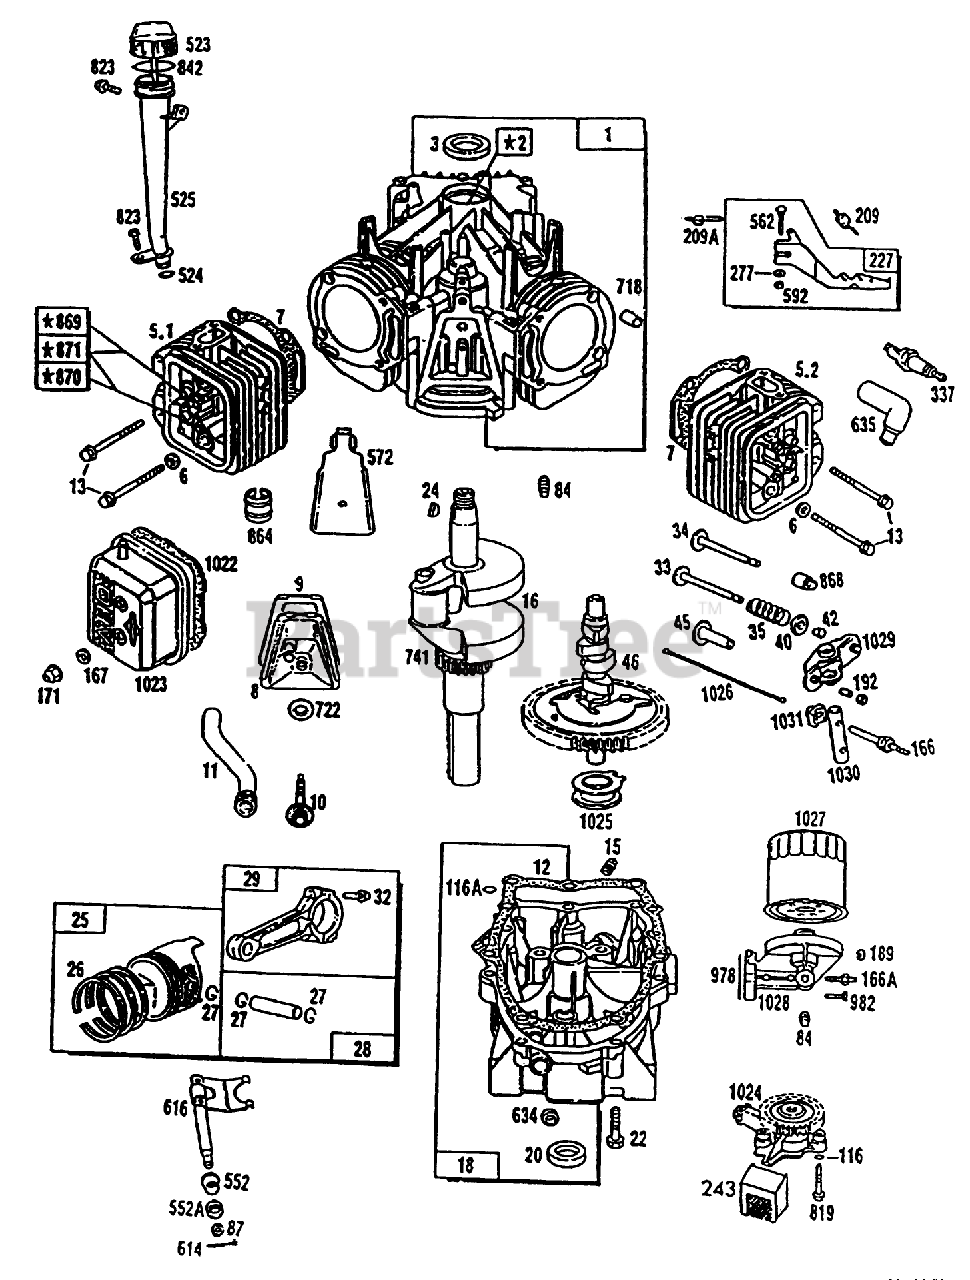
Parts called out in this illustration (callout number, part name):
1	BRIGGS-807511
3	BRIGGS-805101
6	BRIGGS-805193
7	BRIGGS-807986
8	Breather Assembly
9	BRIGGS-805379
11	BRIGGS-805362
12	BRIGGS-805312
13	Screw
18	Cover-Crankcase
20	BRIGGS 805049
22	BRIGGS-805017
24	Key-Flywheel
25	Piston Ass-y (Std.)
26	BRIGGS-870620
27	BRIGGS 805099
28	BRIGGS-807621
29	BRIGGS-807622
32	BRIGGS-805395
33	BRIGGS-807681
34	BRIGGS-807680
35	Spring-Valve
40	BRIGGS-805092
42	BRIGGS-807683
45	BRIGGS 805354
46	BRIGGS-807542
84	Plug-Pipe
87	BRIGGS-805054
116	BRIGGS-805058
116A	BRIGGS-805198
166A	Stud-Oil Filter Adapter
167	BRIGGS-805420
171	BRIGGS 805019
189	BRIGGS-805449
192	BRIGGS-807623
209	BRIGGS-805562
209A	BRIGGS-805453
243	BRIGGS-805312
277	BRIGGS-805018
351	BRIGGS 805169
523	BRIGGS-807516
524	BRIGGS 807663
552	BRIGGS-805412
552A	BRIGGS-805413
562	BRIGGS 805381
572	BRIGGS-805197
592	BRIGGS-805395
614	BRIGGS 805417
616	FORK-GOVERNOR
634	BRIGGS 805416
635	BRIGGS 805529
718	BRIGGS-805103
741	BRIGGS-805675
819	BRIGGS 805057
823	BRIGGS 805317
842	BRIGGS-805012
864	BRIGGS 805083
868	BRIGGS-805094
869	BRIGGS-805085
870	BRIGGS-805086
871	BRIGGS-805084
978	BRIGGS 805250
982	BRIGGS-805030
1022	BRIGGS-805028
1023	BRIGGS-805100
1024	BRIGGS-807546
1025	BRIGGS-805313
1026	OBTAIN LOCALLY
1028	BRIGGS 805292
1029	BRIGGS-807557
1030	BRIGGS-805342
